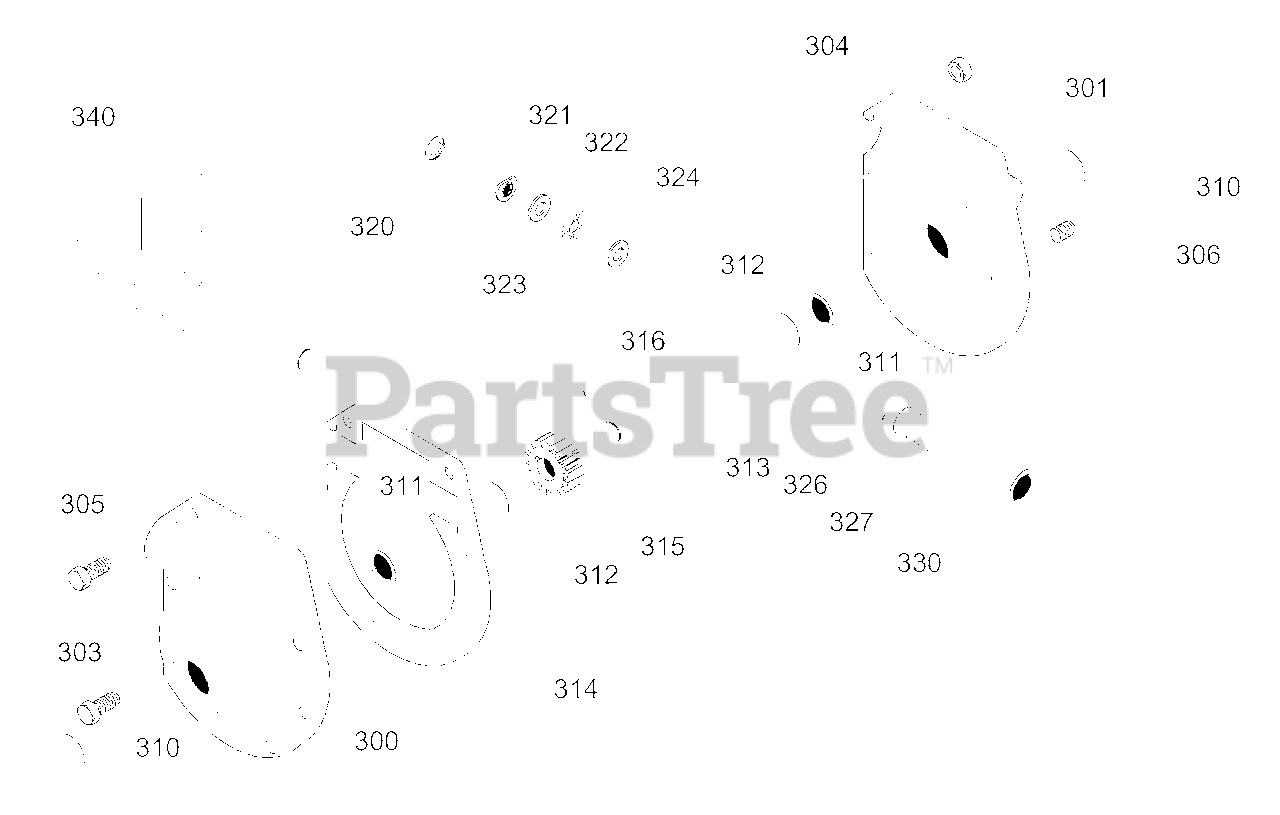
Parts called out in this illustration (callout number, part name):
300	CASE, GEAR RH
301	CASE, GEAR LH
303	SCREW 5/16-24X1.00
304	NUT, 5/16-24 HEXWDFLLK
305	SCREW, 5/16-24X1.50
310	SEAL, OIL
311	BEARING, SLEEVE
312	FLATWASHER
313	SHAFT, AUGER OUTPUT 22"
314	GASKET, GEAR BOX
316	KEY, WOODRUFF #91
320	RING, QUAD
321	BEARING, FLANGE
322	FLATWASHER .752X1.24X.093
323	BEARING, ROLL
324	FLATWASHER .752X1.24X.093
326	KEY, HI-PRO 606
330	BRING, SLEV .752IDX.88ODX.755
340	IMPELLER, ASSY
